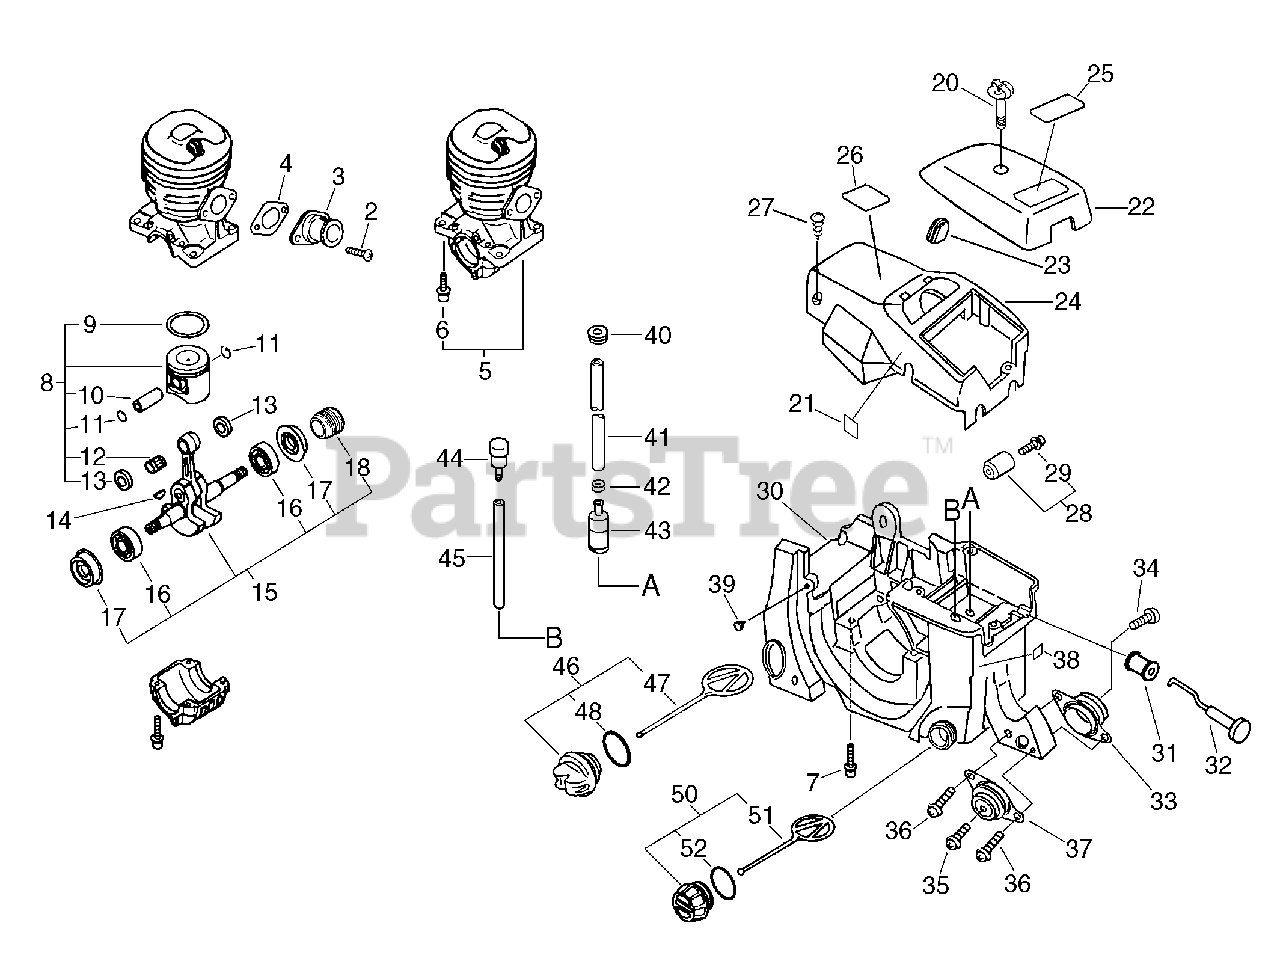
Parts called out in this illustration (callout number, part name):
2	SCREW - 5X12
3	ADAPTOR, INTAKE
4	GASKET, INTAKE
5	CRANKCASE KIT
6	SCREW - 5X22
7	SCREW - 5X30
8	PISTON KIT
9	RING, PISTON
10	PIN, PISTON
11	RING, RETAINING
12	BEARING, NEEDLE
13	SPACER, PISTON
15	CRANKSHAFT ASSY
16	BEARING, BALL - 6201
17	SEAL, OIL
18	GEAR - WORM
20	THUMBSCREW
21	LABEL - CAUTION
22	COVER, AIR FILTER
24	COVER, CYLINDER
25	LABEL - MODEL
26	LABEL - CAUTION
27	SCREW - 4X16
28	CHAIN CATCHER KIT
29	SCREW - 5X20 -- TAPPING
30	COVER, ENGINE
32	ROD, CHOKE
33	CUSHION
34	SCREW - 5X25
35	SCREW - 5X14
36	SCREW - 4X22
38	LABEL - STOP
39	VENT, TANK
41	PIPE, FUEL - SPIRAL
42	CLIP - 6.5
43	FILTER, FUEL
44	VENT, FUEL TANK
45	PIPE - 3X5X50
46	CAP ASSY
47	CONNECTOR, CAP
48	O-RING - 25
50	CAP ASSY
51	CONNECTOR, CAP
52	O-RING - 22
